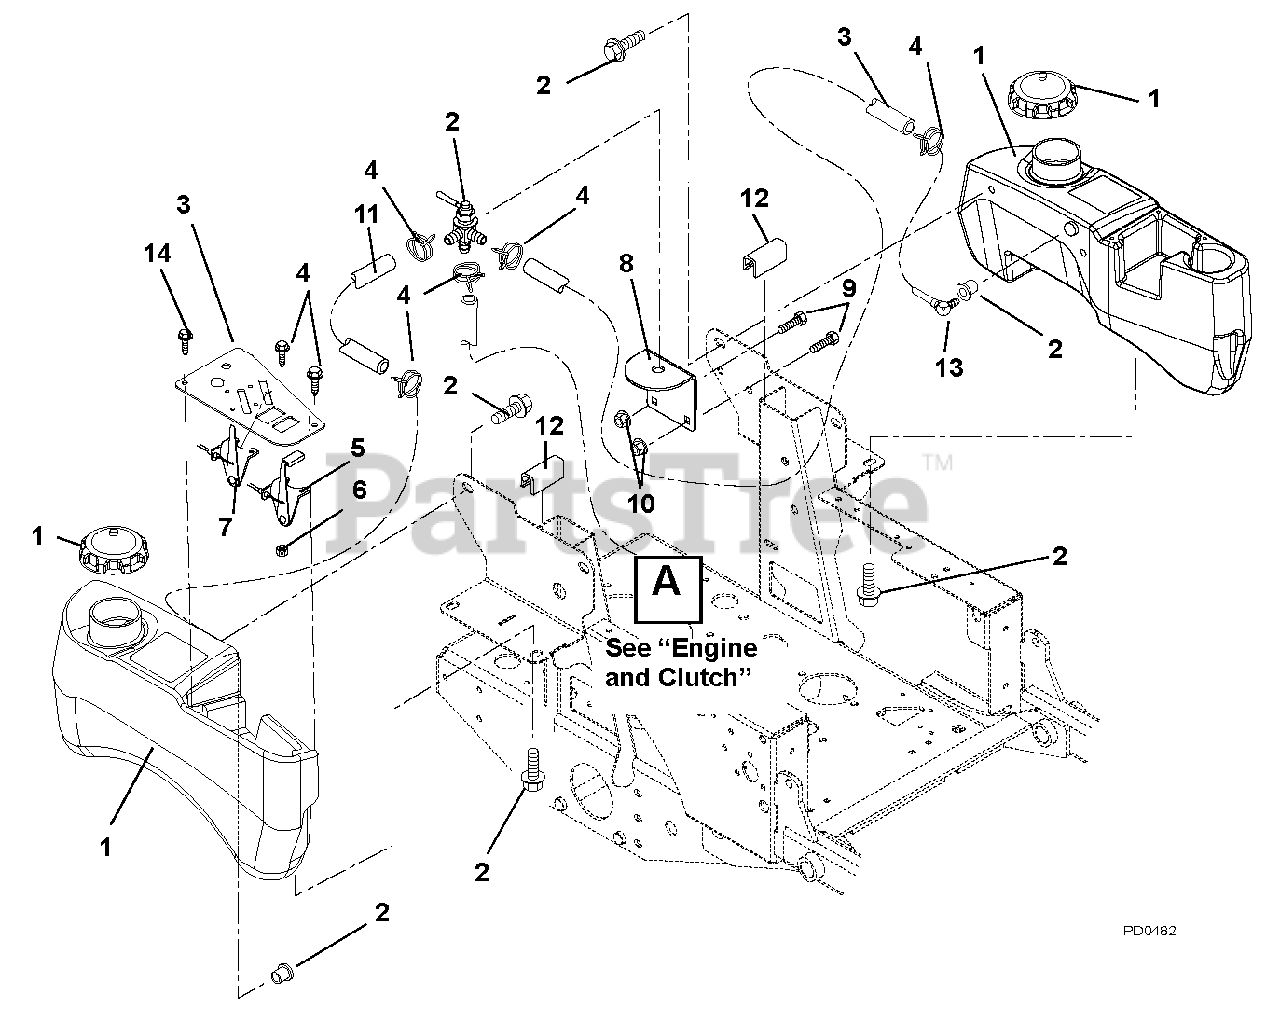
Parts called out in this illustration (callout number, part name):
1	Tank, Fuel Right Hand (991301 S/N 101 – 2499)
1	Tank, Fuel Left Hand (991301 S/N 101 – 2499)
1	Cap, Fuel (991301 S/N 101 – 2499)
2	Bolt, SEMS .31-18 x .62 (S/N 101 – 2499)
2	Valve, Fuel
2	Grommet (Orange color will not replace black color)
3	Hose, Gas Line .25" I.D.
3	Panel, Control
4	Hose, Clamp
4	Screw, Machine 10-24 x .50 Hex Washer Head
5	Cable, Throttle
6	Nut, Locking Nylon 10-24 with Insert
7	Cable, Choke
8	Bracket, Fuel Valve Mounting
9	Bolt, Round Head Square Neck .31-18 x .75
10	Nut, Nyloc Flange 5/16-18
11	Hose, Gas Line .25" I.D.
12	Cowl Strip 1.75" Long
13	Assembly, Small Tank Fuel Pick-up
14	Screw, Machine 10-24 x .38
